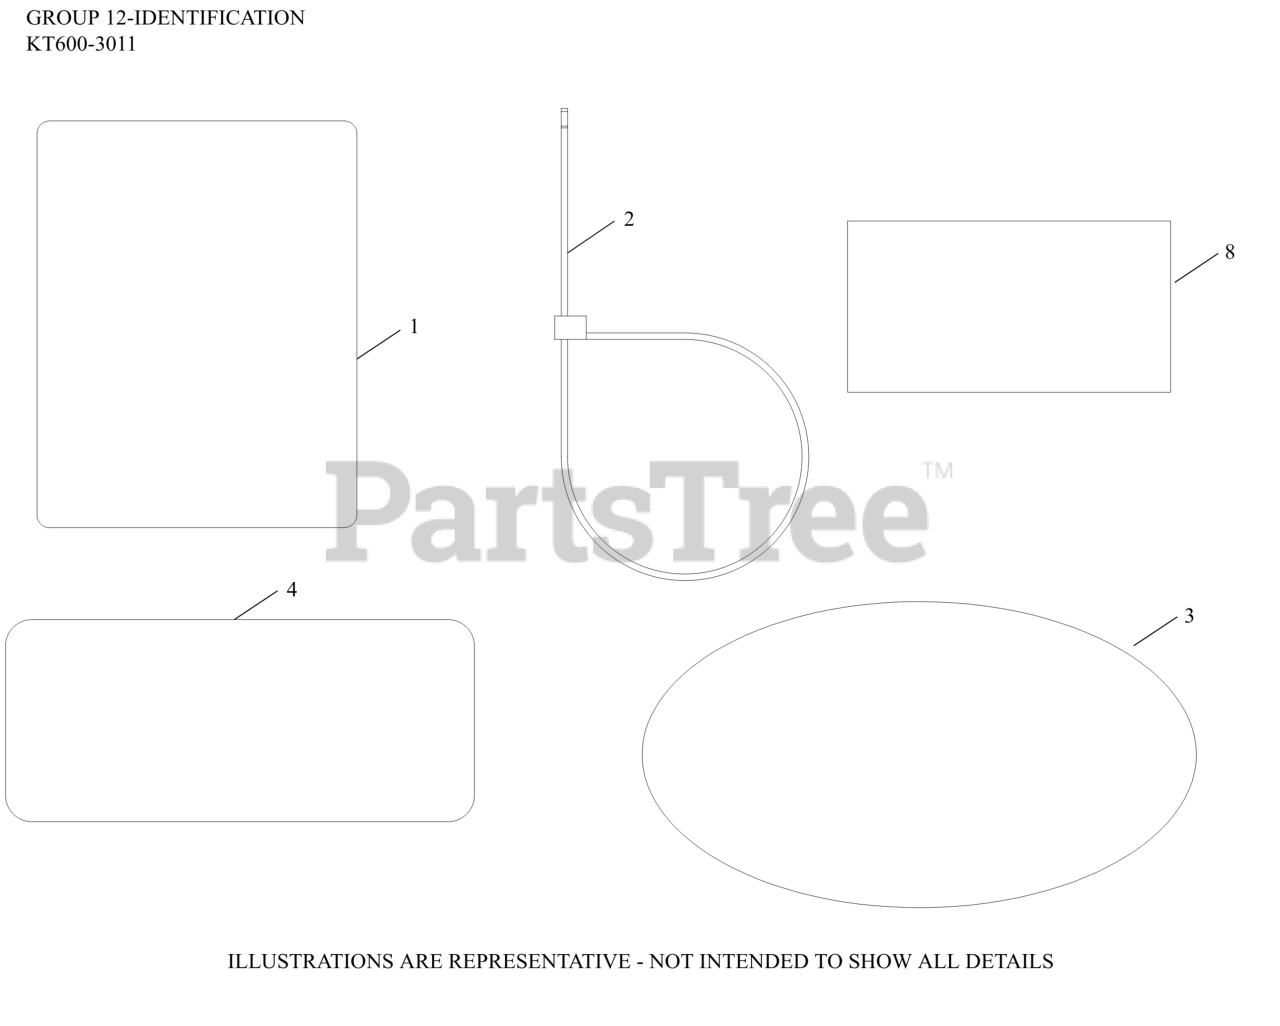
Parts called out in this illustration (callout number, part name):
1	LABEL, CLEAR LAMINATION
3	LABEL, 6000 SERIES (17HP)
4	LABEL, CANADIAN COMPLIANCE
8	DECAL, USA
